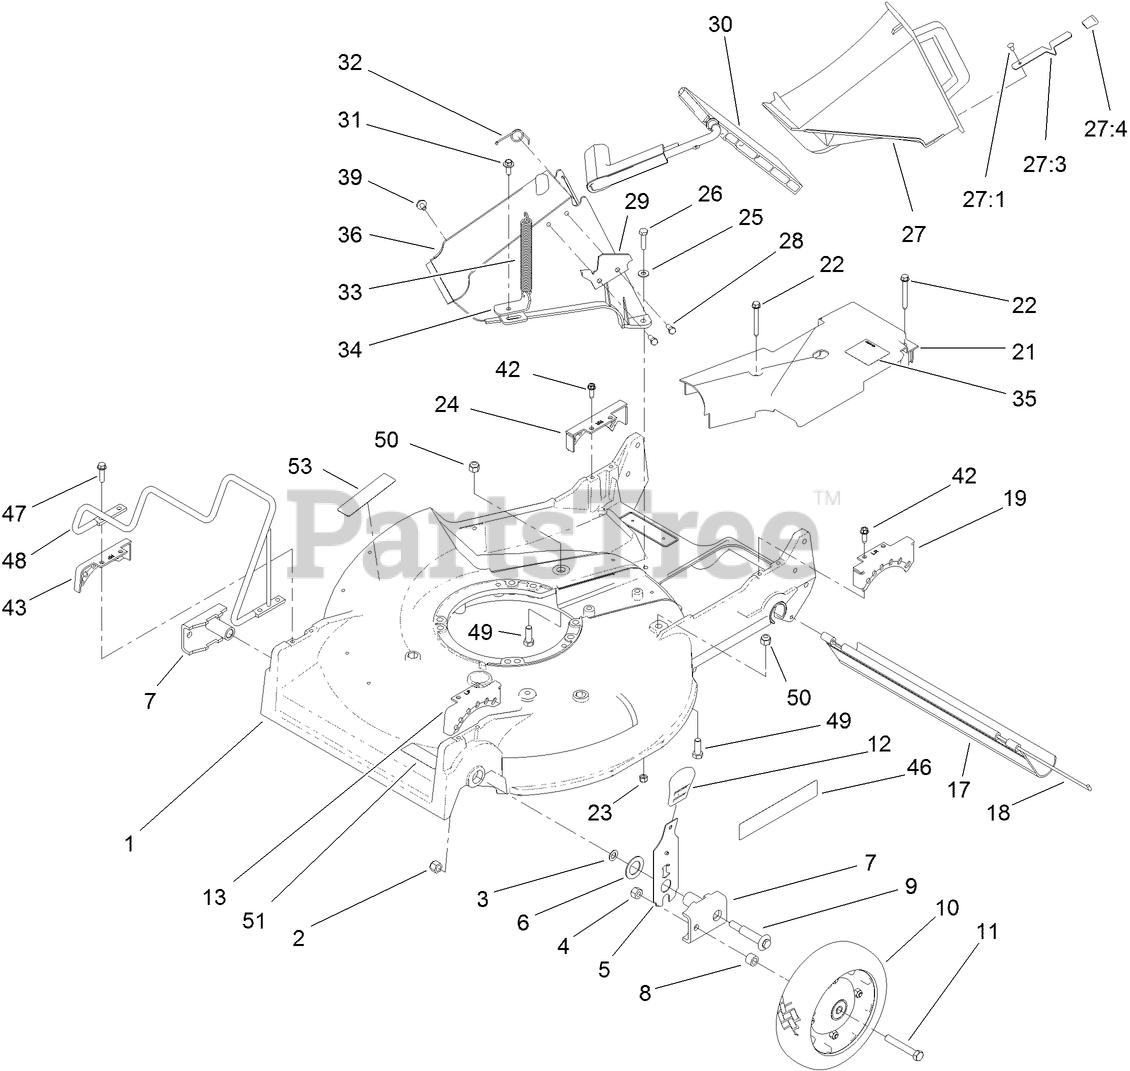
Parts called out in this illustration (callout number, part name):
1	HOUSING ASM
2	NUT-LOCK
3	WASHER
4	NUT-LOCK, CONE
5	FRONT SPRING ARM ASM
6	WASHER-THRUST
7	ARM-PIVOT, FRONT
8	SPACER-WHEEL
9	SCREW-SHOULDER
10	WHEEL AND TIRE ASM
11	SCREW-HH
12	KNOB-HOC
13	QUADRANT-FRONT, LH
17	SHIELD-TRAILING
18	ROD-SHIELD
19	QUADRANT-REAR, LH
21	COVER-BELT
22	SCREW-HWHTF
23	NUT-LOCK, NI
24	QUADRANT-REAR, RH
25	WASHER-FLAT
26	SCREW-HH
27	DISCHARGE PLUG ASM
27:1	RIVET-HEAD, FLAT
27:3	LATCH-PLUG, DISCHARGE
27:4	GRIP-LATCH
28	SCREW-PLASTITE
29	LATCH-PLATE
30	DISCHARGE DOOR ASM
31	SCREW-HWH
32	RETAINER-DOOR
33	SPRING-DOOR
34	BRACKET-SPRING
35	DECAL-GREASE
36	TUNNEL-DISCHARGE
39	SCREW AND WASHER ASM
42	SCREW-HWHTF
43	QUADRANT-FRONT, RH
47	SCREW-HWHTF
48	GUARD-ENGINE
49	SCREW-HH
50	NUT-LOCK, NI
51	DECAL-BLADE
53	DECAL-ARRESTER, SPARK
